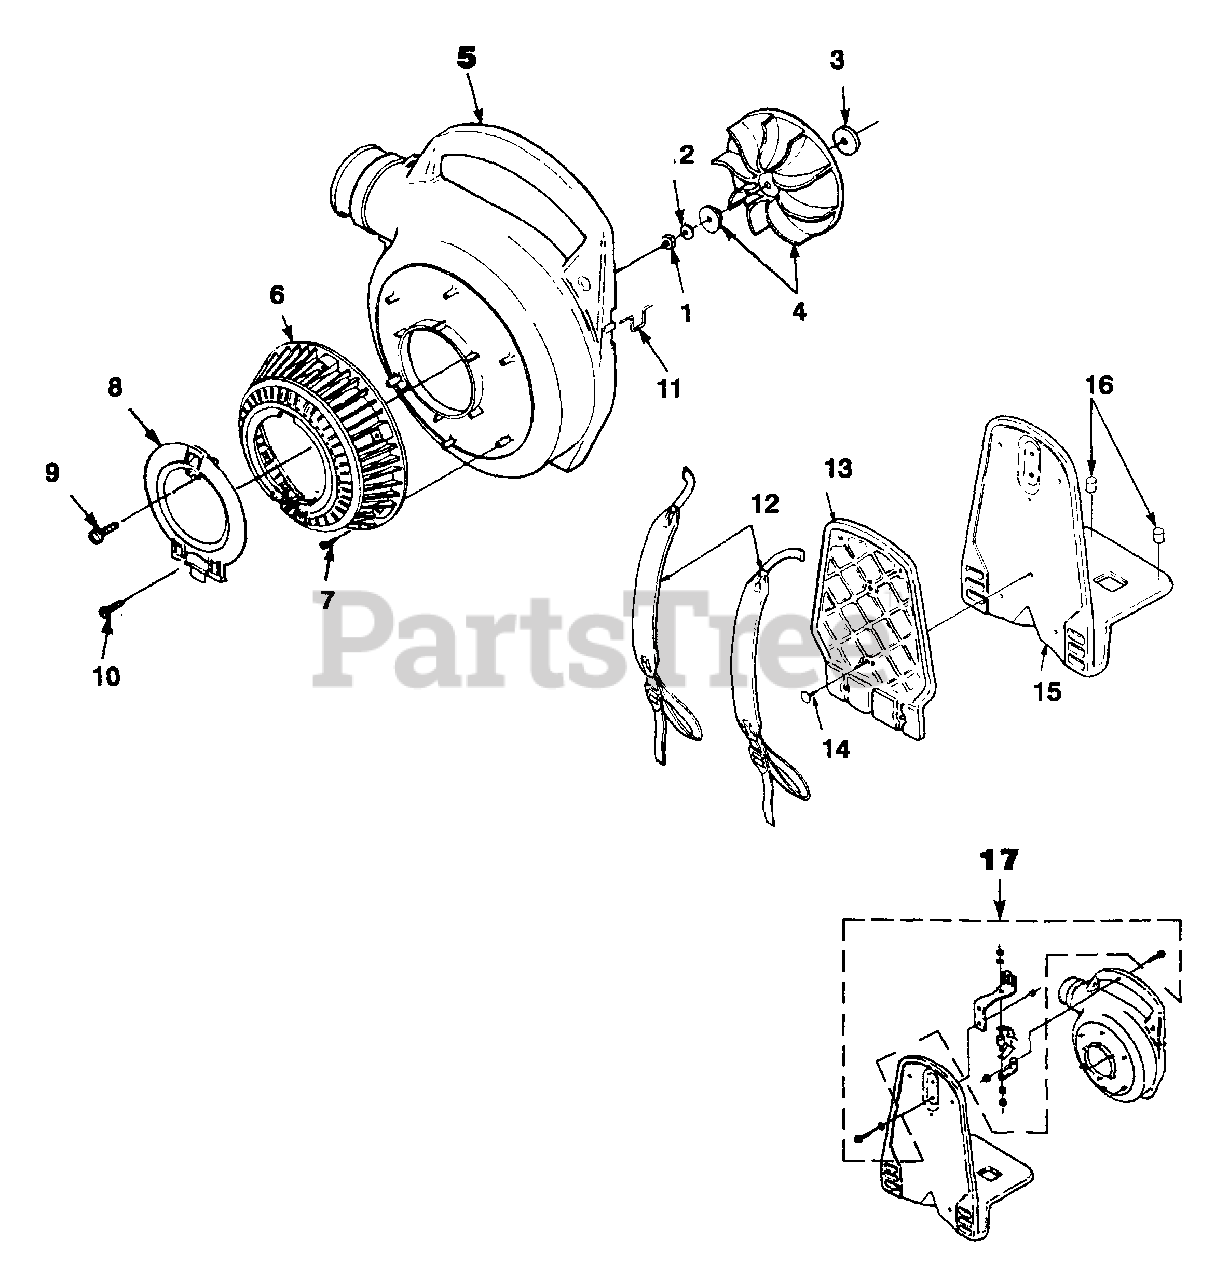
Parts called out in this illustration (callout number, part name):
1	Hex Nut (3/8-24)
2	Bellville Washer (3/8")
3	Flat Washer
4	Blower Fan Kit
5	Volute Housing Kit,Outer
6	Blower Vac Grille Kit
7	Screw-Thread Form. (10-24 x 3/4")
8	Access Cover
9	Screw-Thread Rolling (#10 x 5/8")
10	Screw-Thread Form. (#8 x 1/2")
11	Wire Loop
12	Shoulder Harness
13	Foam Pad
14	Push Clip
15	Blower Frame
16	Vibration Isolator One
17	Vibration Isolator Kit
